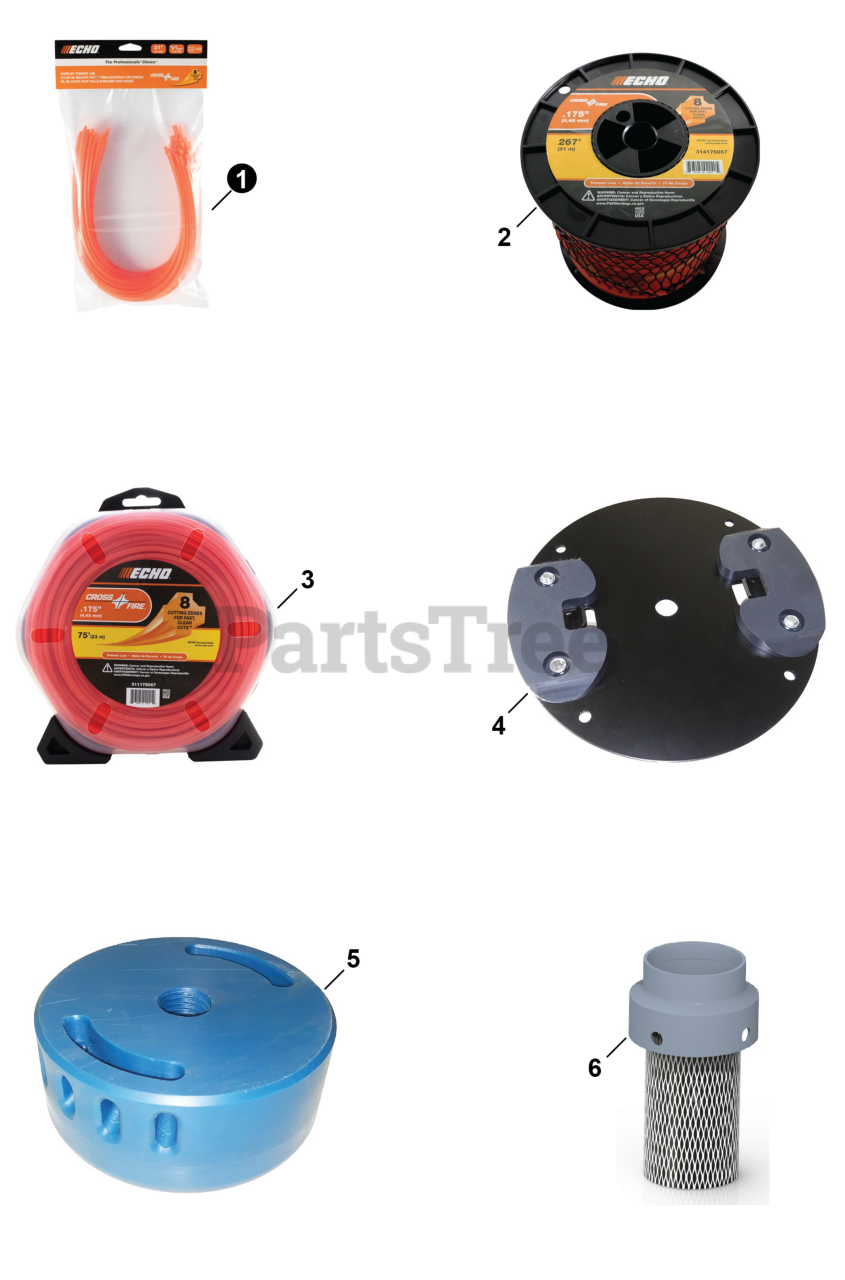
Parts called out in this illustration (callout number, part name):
1	CUTTING LINE, HEAVY DUTY - 0.155 DIA (50 PER PACK)
1	50 COUNT 21"" .175 X-FIRE
2	155 DIA, CROSS-FIRE ®(3 LB. SPOOL)
2	175 DIA, CROSS-FIRE®(3 LB. SPOOL)
3	155 DIA, CROSS-FIRE ®(1 LB. DONUT)
3	175 DIA, CROSS-FIRE ®(1 LB. DONUT)
4	BULK ROPE - 3x850
5	KIT, NO SPARK MOW BALL
6	KIT, BRIGGS WT SPARK ARRESTOR
